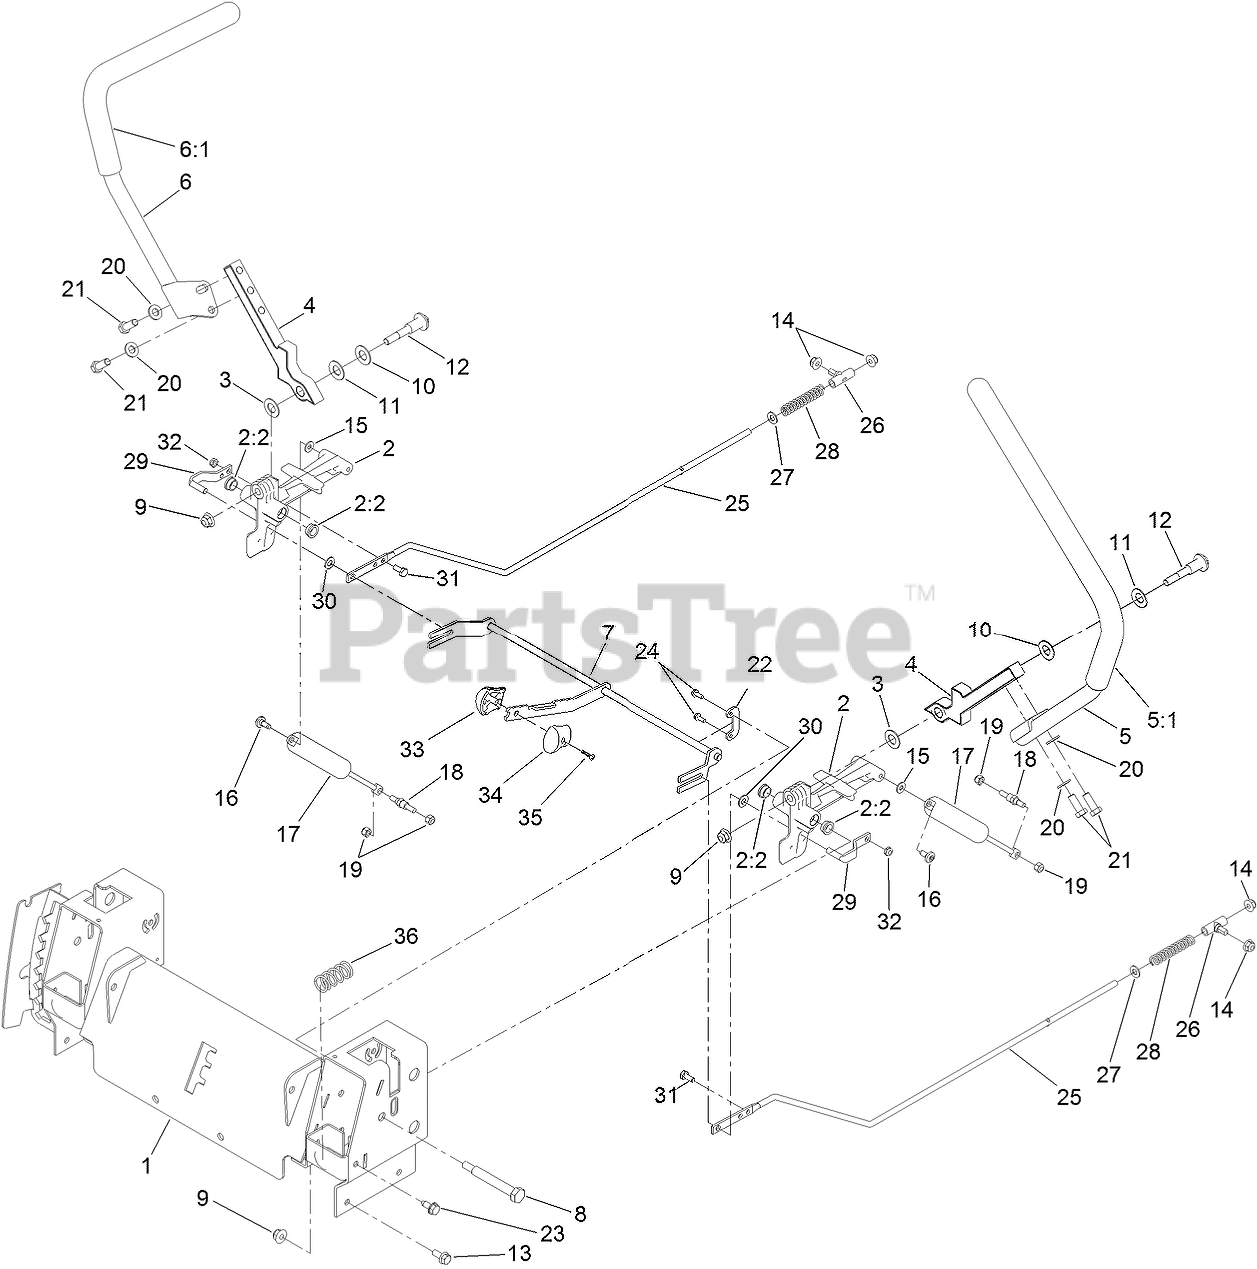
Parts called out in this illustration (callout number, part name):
1	CONTROL BOX ASM
2	ACTUATOR ARM ASM
2:2	BUSHING-FLANGE
3	WASHER-NYLON
4	LEVER-CONTROL
5	HANDLE-CONTROL, LH
6	HANDLE-CONTROL, RH
7	SPEED CONTROL ASM
8	BOLT-PIVOT
9	NUT-HF, NI
10	WASHER
11	WASHER-BELLEVILLE
12	BOLT-PIVOT
13	SCREW-HHF
14	NUT-HF, NI
15	WASHER
16	SCREW-SHOULDER
17	DAMPER
18	STUD-DAMPER
19	NUT-LOCK, NI
20	WASHER-FLAT
21	SCREW-HH
22	RETAINER
23	SCREW-HWHTF
24	SCREW-TAPTITE
25	ROD-HYDRO
26	MOUNT-ROD, HYDRO
27	WASHER-PLAIN
28	SPRING-RETURN, NEUTRAL
29	PIN-ROD, HYDRO
30	SPACER-NYLON
31	SCREW-HH
32	NUT-LOCK, NI
33	KNOB-RH
34	KNOB-LH
35	SCREW-PPH
36	SPRING-RETURN
